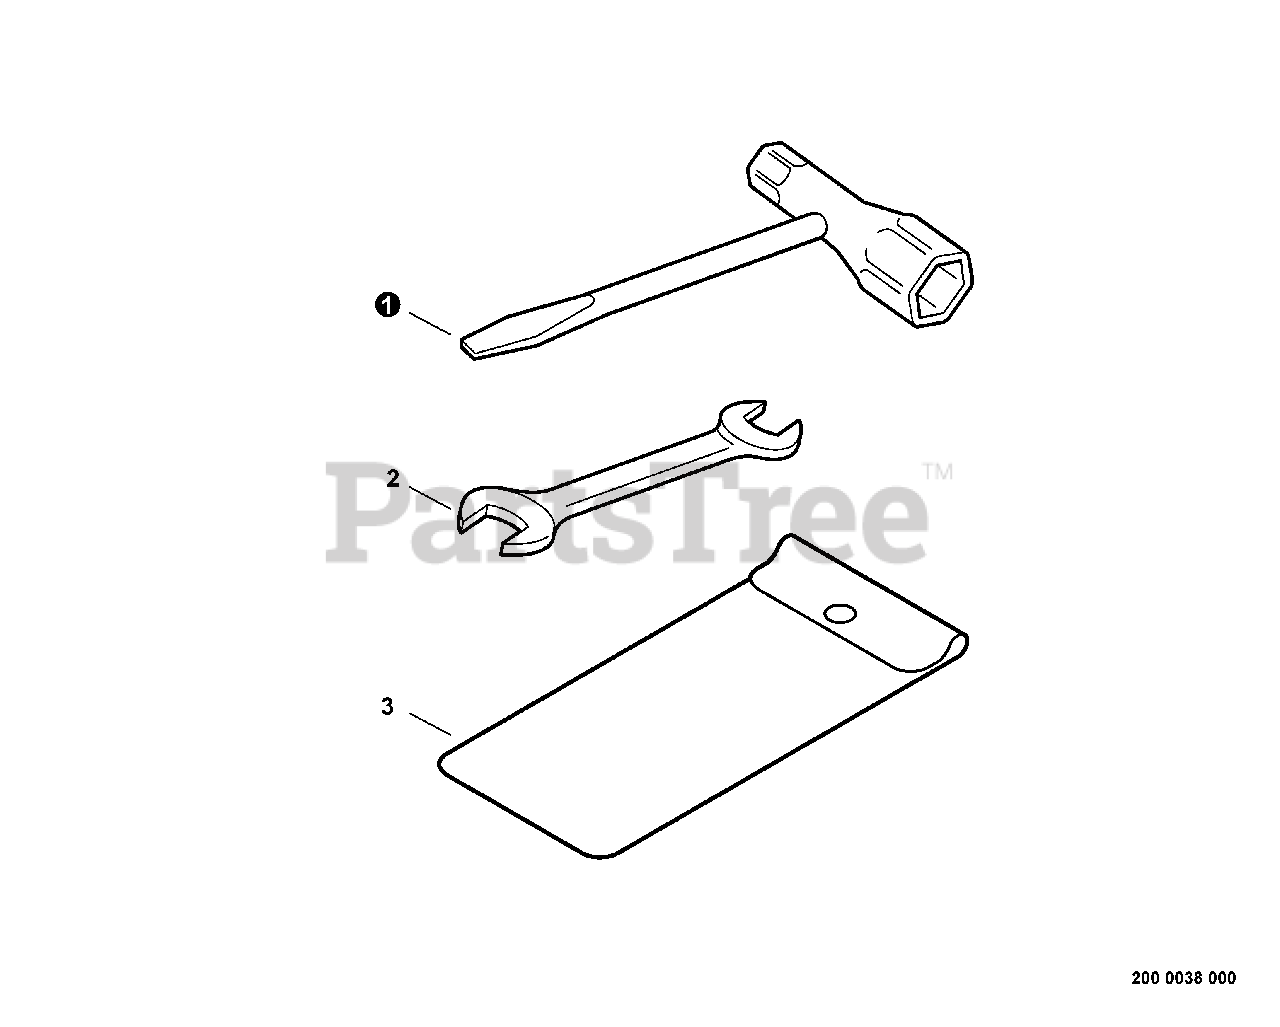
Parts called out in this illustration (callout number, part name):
1	T-WRENCH - 17X19mm
2	SPANNER - 8X10mm
3	BAG, TOOL
